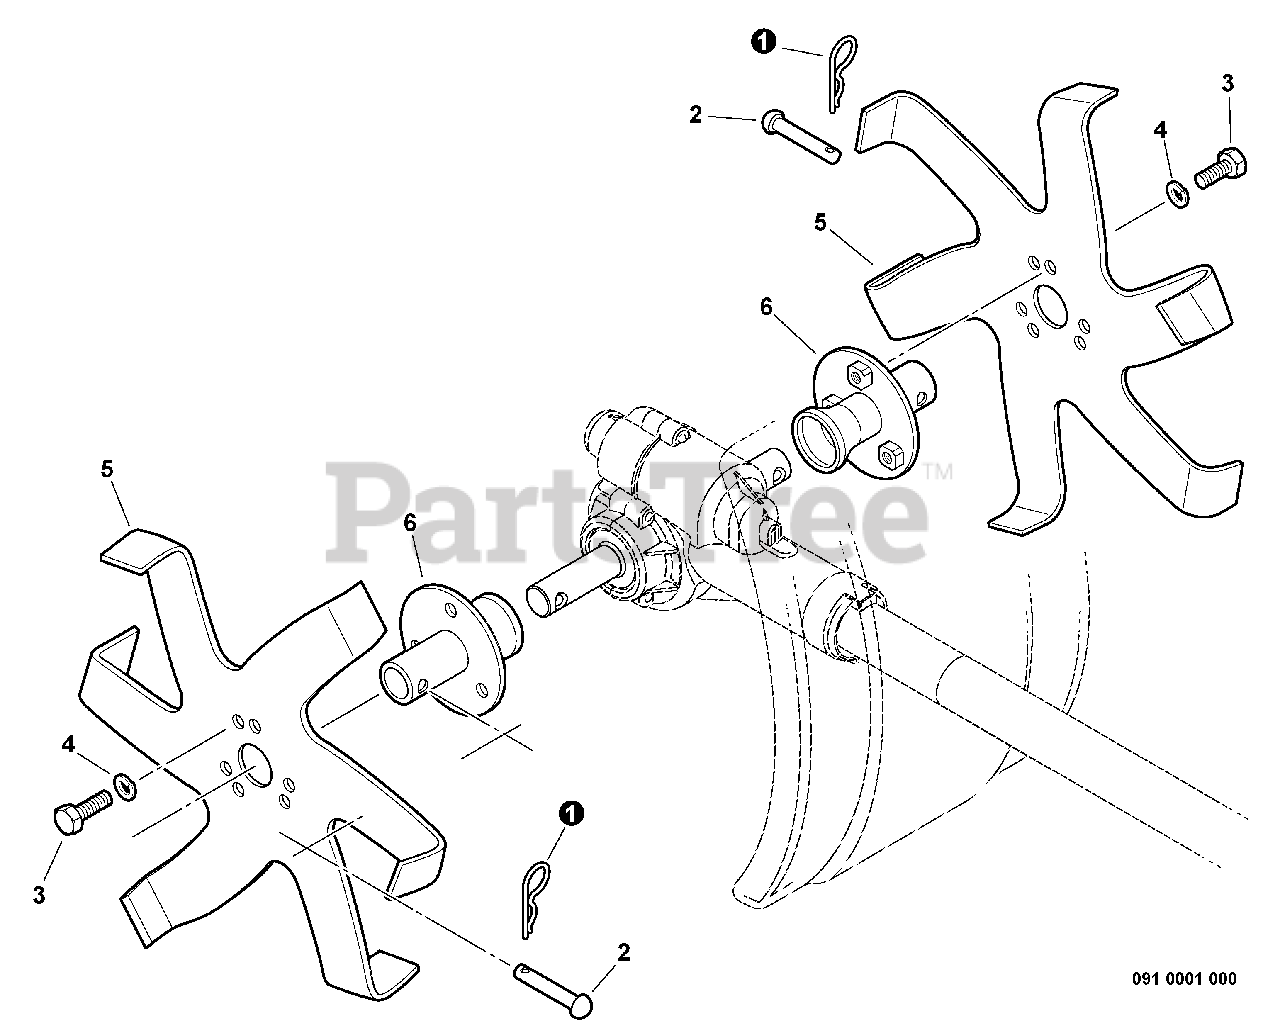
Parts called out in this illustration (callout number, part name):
1	PIN, SPLIT
2	PIN - CLEVIS
3	BOLT - 6X10
4	LOCKWASHER - 6
5	BLADE, CULTIVATOR
6	HUB, CLUTCH
